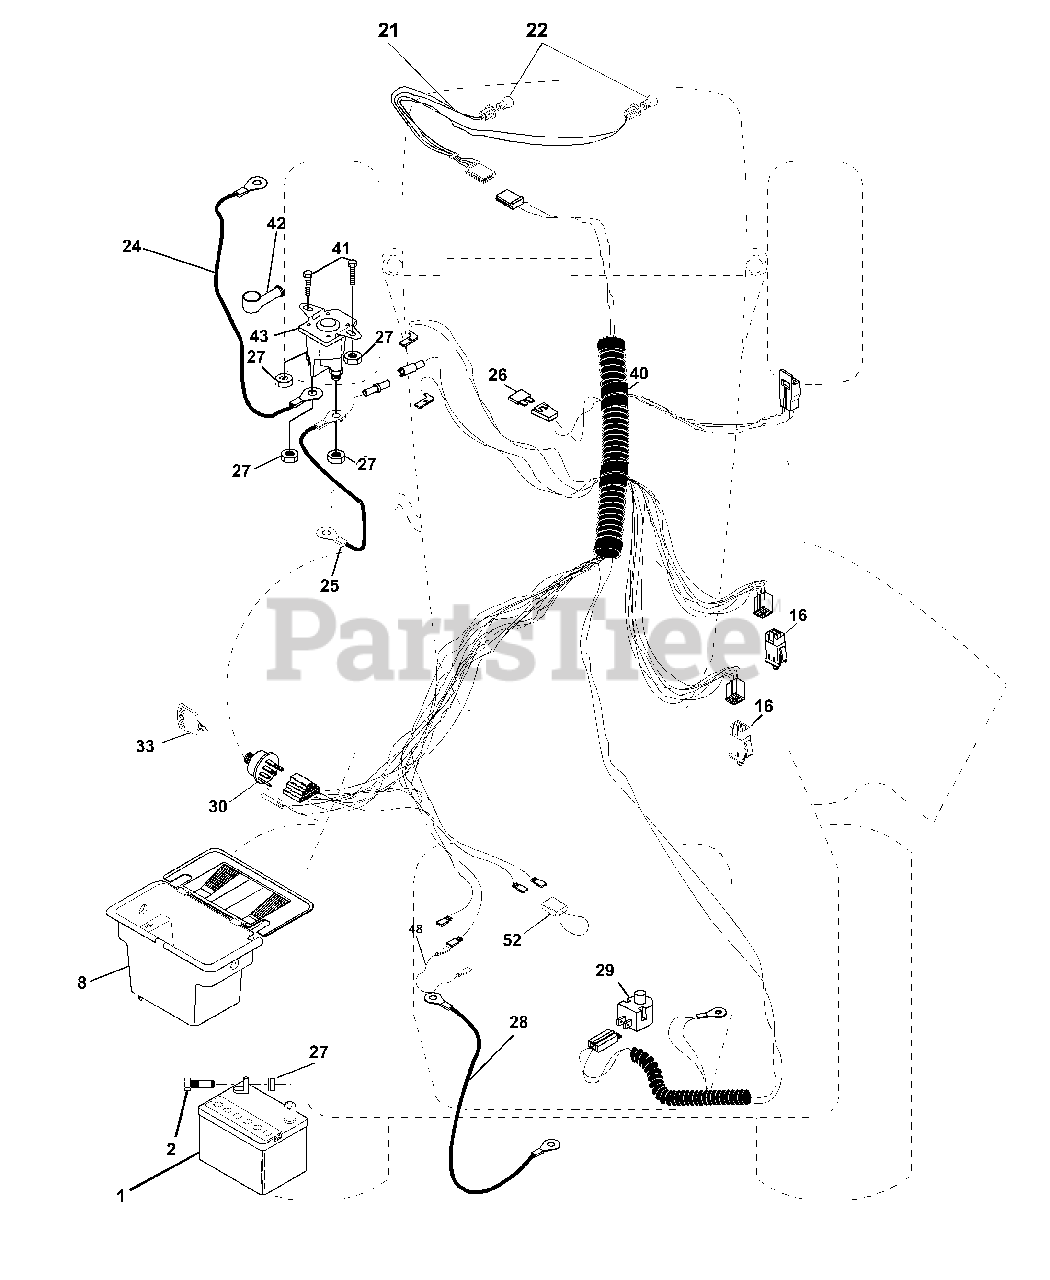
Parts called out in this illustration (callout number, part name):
1	Battery 12 Volt 25 Amp
2	Bolt Hex Hd 1/4-20unc X 3/4
8	Case Battery
16	Switch Interlock Push -In
21	Harness Asm Light W/4152J
22	Bulb Light #1156
24	Cable Battery 6 Ga 11"red
25	Cable Battery 6 Ga w/16 wire,red
26	Fuse 15 AMP
27	Nut Keps Hex 1/4-20 unc
28	Cable Ground 6 Ga 12" black
29	Switch Plunger Nc Gray
30	Switch Ign
33	Key Ign
40	Harness Ign
41	Bolt Blk Fin Hex 1/4-20 X 1/2
42	Cover Terminal Red
43	Solenoid
48	Adaptor Ammeter Rectangular
52	Protection Wire Loop
